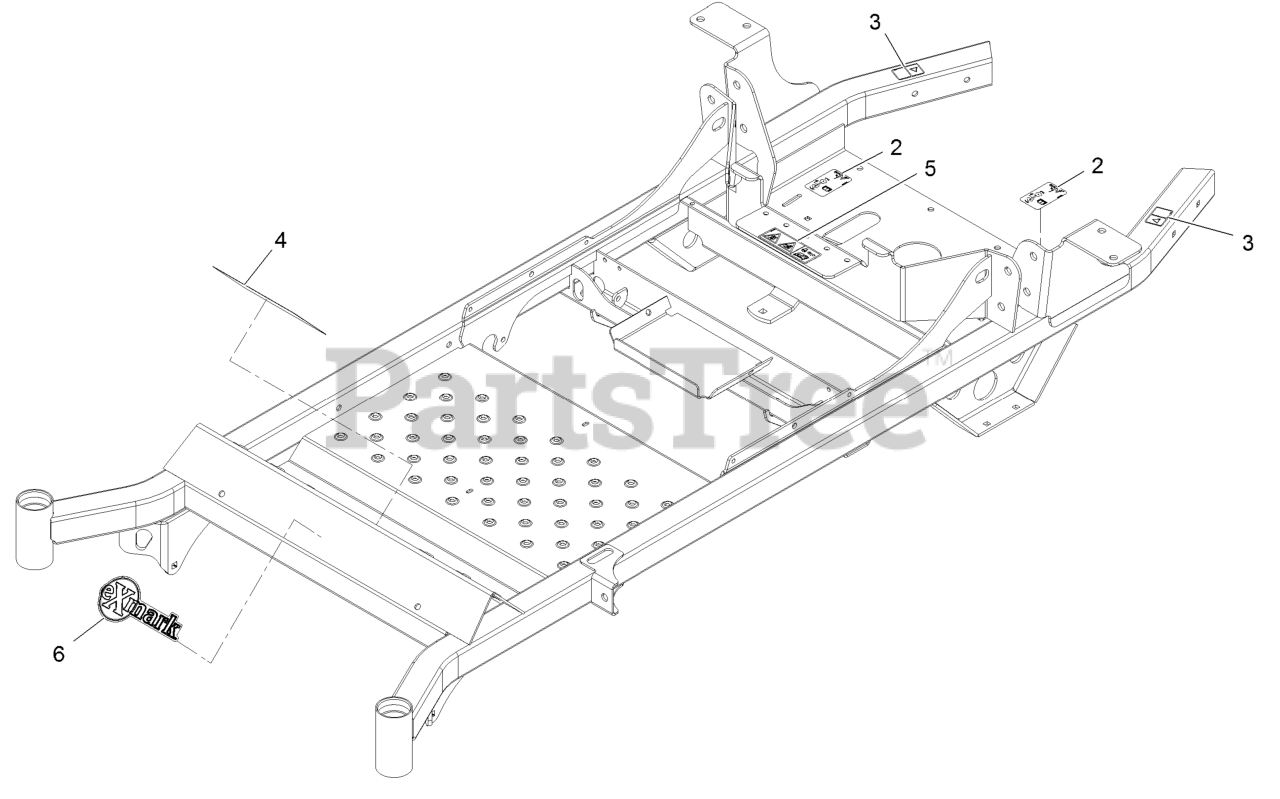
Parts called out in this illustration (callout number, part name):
2	DECAL-RELEASE, DRIVE
3	DECAL-WARNING
4	DECAL-DANGER
5	DECAL-WARNING
6	DECAL, EXMARK LOGO
